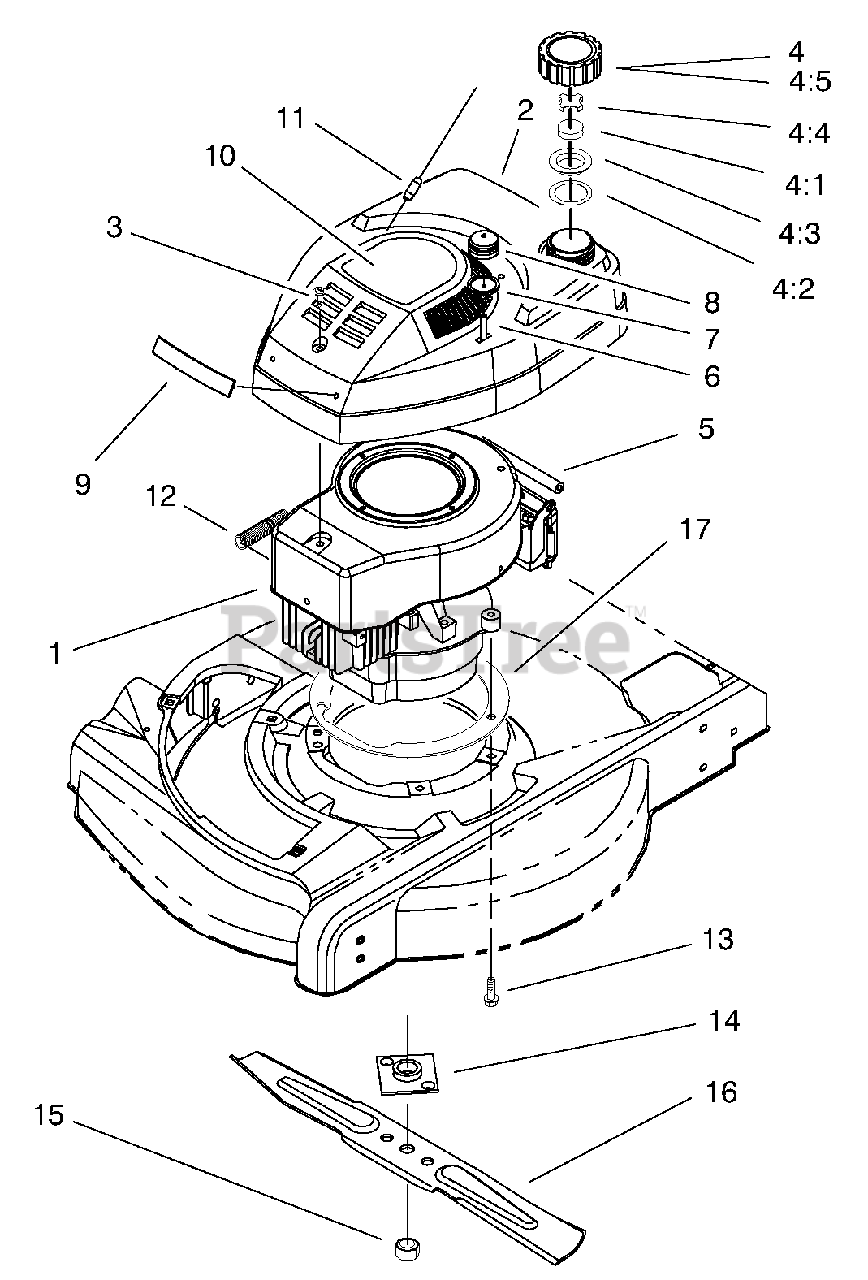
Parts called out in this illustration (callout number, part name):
1	Engine ASM
2	Tank & Shroud ASM
3	Screw-Sems
4	Fuel/Oil Cap ASM
4:1	Foam Baffle
4:2	Gasket-Fuel Cap
4:3	Cover-Fuel Cap Baffle
4:4	Baffle-Gas Cap
4:5	Cap-Fuel/Oil
5	Gas Line
6	Hose-Primer
7	Body-Primer
8	Bulb-Primer
9	Applique-Shroud
10	Decal-Shroud Top
11	Rope-Stop
12	Spring-Compression
13	Screw-Engine Mount
14	Plate & Collar ASM
15	Blade-21" Whirl
16	Nut-Blade
17	Plate-Engine
